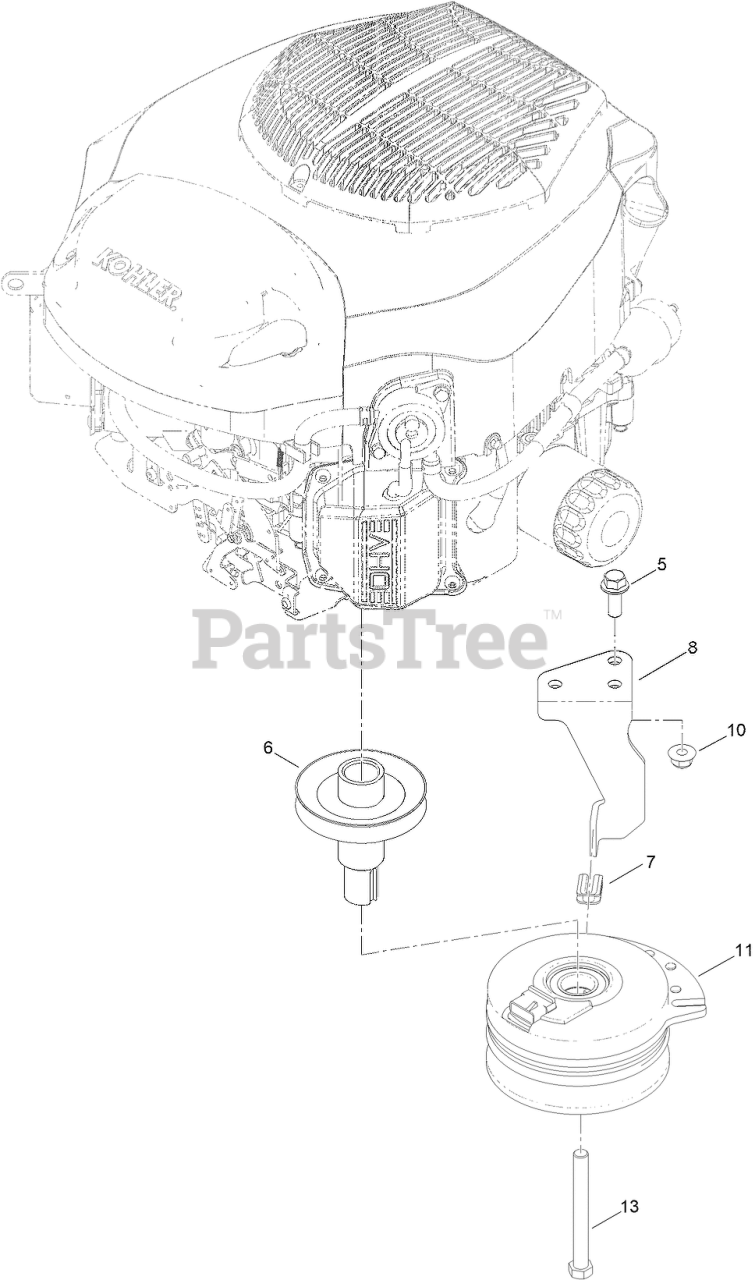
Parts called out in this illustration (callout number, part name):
5	SCREW-HHF
6	PULLEY-ENGINE
7	ISOLATOR-CLUTCH
8	STOP-CLUTCH
10	NUT-HF, NI
11	CLUTCH-ELECTRIC
13	SCREW-HH
